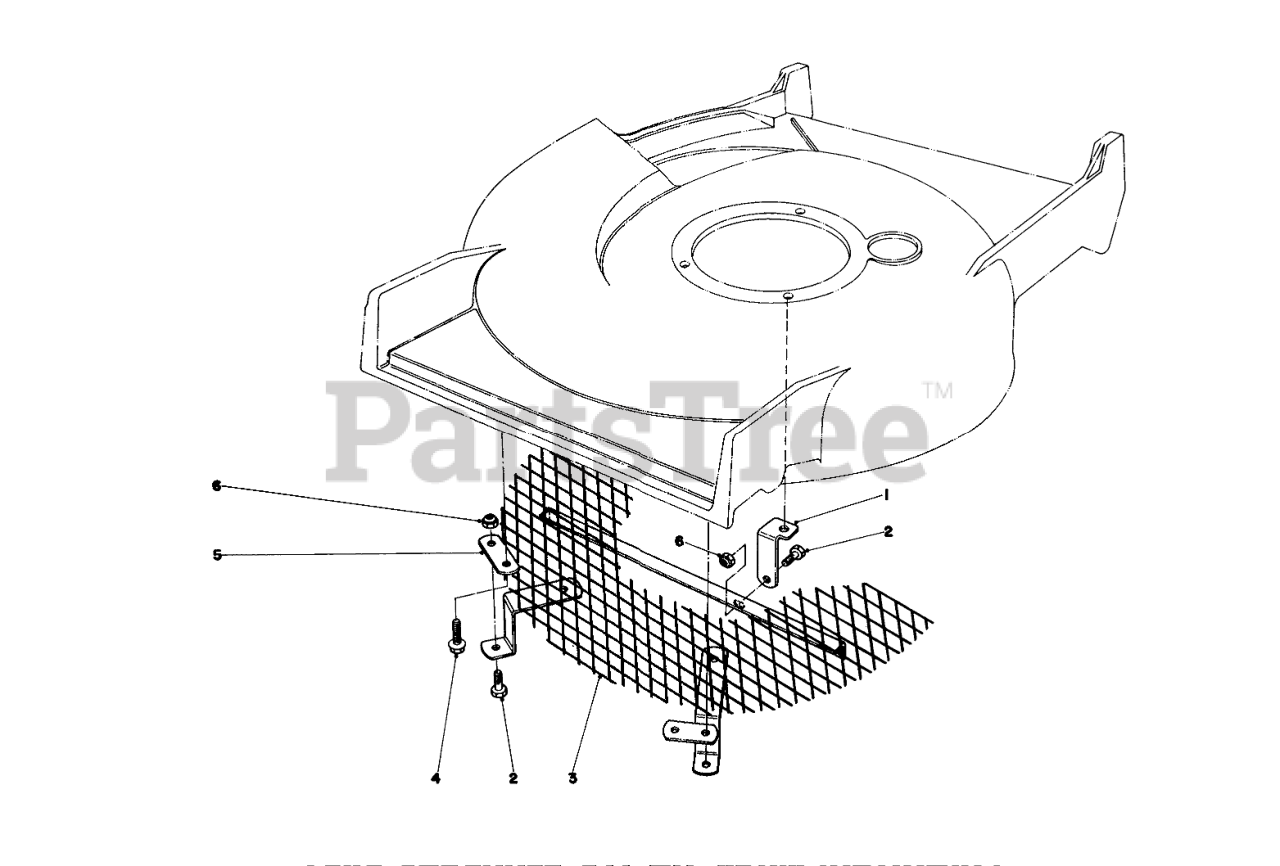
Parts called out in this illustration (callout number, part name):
1	Support Bracket
2	SCREW-HH
3	Screen
4	SCREW-HWHTF
5	ANCHOR
6	NUT-LOCK, NI
